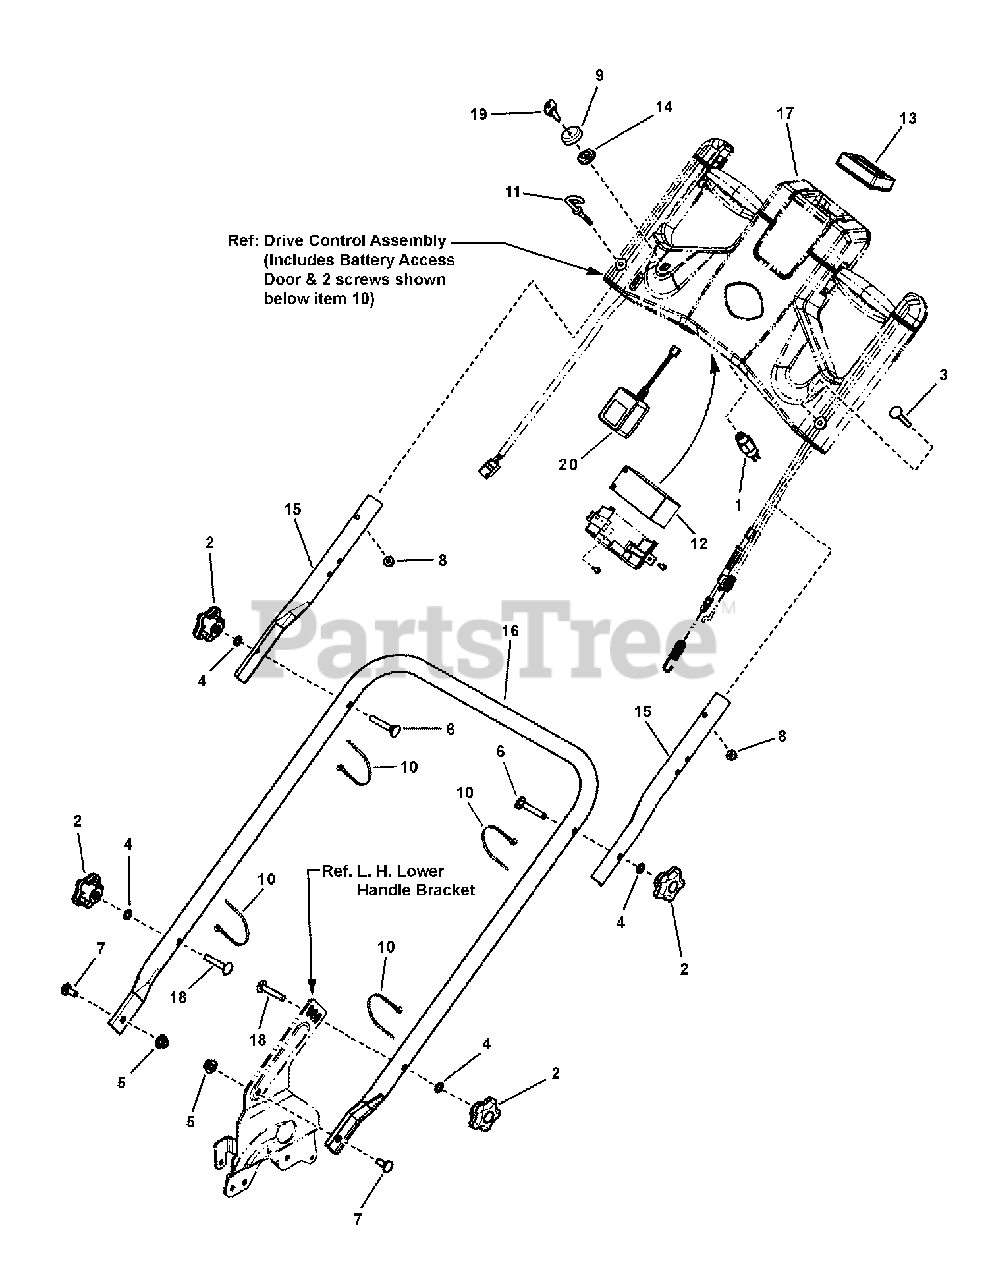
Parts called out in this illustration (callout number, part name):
1	SWITCH, ES, Start/Run
2	KNOB, Handle, (5/16-18 internal threads) 5-Prong
3	BOLT, 1/4-20 x 1-3/4" Round Head Square Neck, GR 2, YZ
4	WASHER, 5/16" Internal Tooth Lock
5	NUT, 5/16-18 Large Flange Center Lock
6	BOLT, 5/16-18 x 2" Curved Head Square Neck, GR 2
7	BOLT, 5/16-18 x 3/4" Round Head Short Square Neck Carriage, GR 5
8	NUT, 1/4-20 Hex Flange (Esna), YZ
9	BEZEL, Black
10	WIRE TIE, 11 Inch Standard Black Nylon
11	ROPE GUIDE, (1/4-20 thread)
12	BATTERY, 12V DC, 1.3A / HR
13	METER, Service Indicator
14	NUT, Plastic, 5/8-32
15	HANDLE, Connecting, 21" / 22" WBM
16	HANDLE, Lower
17	ASSEMBLY, Drive Control, Snapper Electric Start
18	BOLT, 5/16-18 x 1-3/4" Short Square Neck Carriage, GR 5
19	KEY, Ignition, Pair
20	CHARGER, Battery, 14V 260MA, 120V AC
